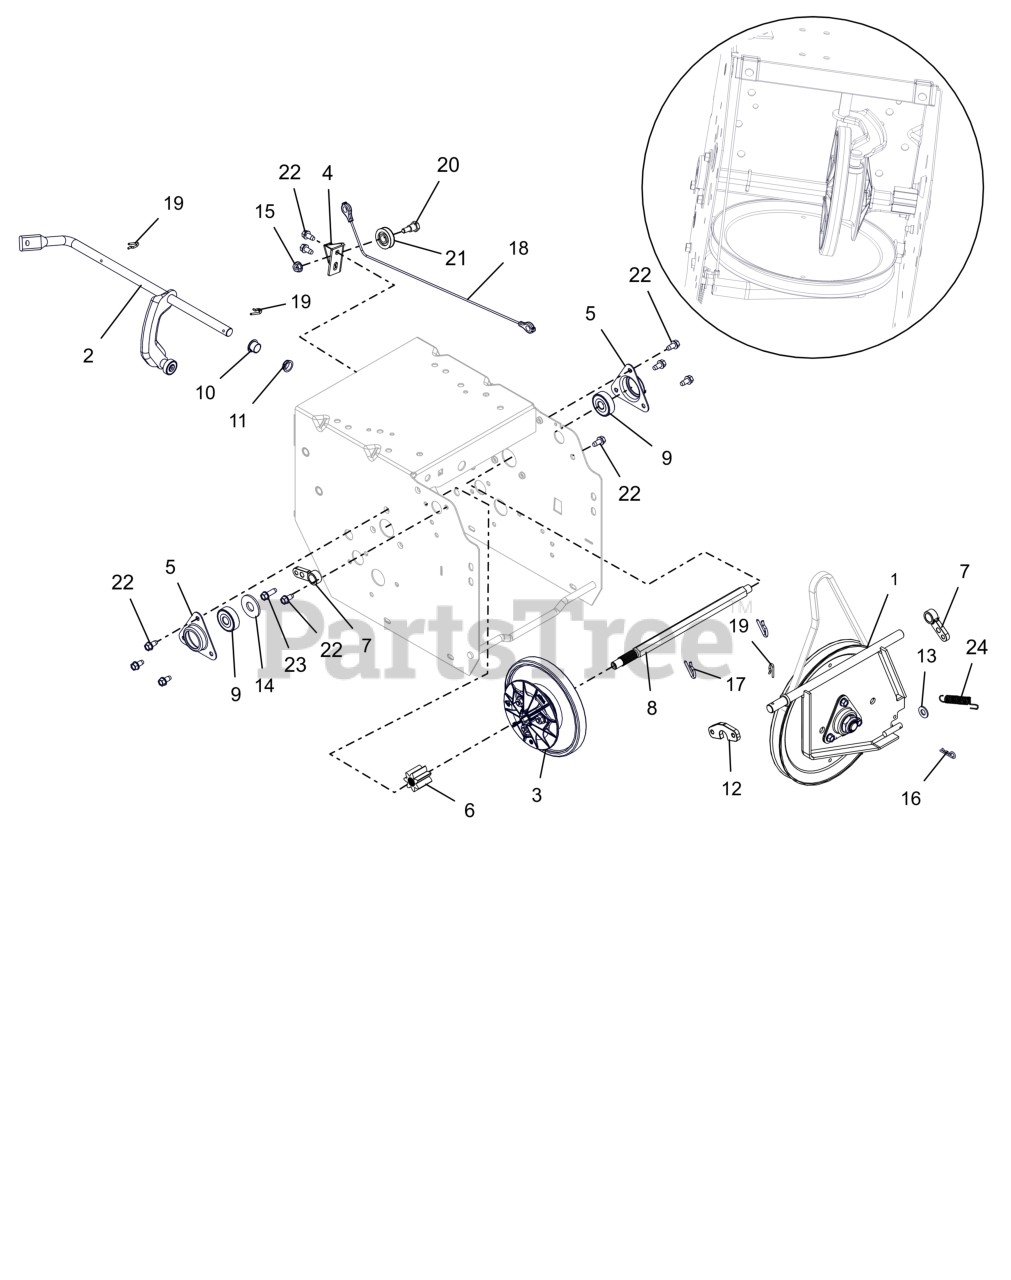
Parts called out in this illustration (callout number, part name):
1	PLATE, SWING - ASSEMBLY
2	ARM, SHIFT-SMALL DASH (ASSY)
3	DISC, FRICTION DRIVE-ASSEMBLY
4	BRACKET, CABLE PULLEY
5	FLANGE, BEARING
6	GEAR, PINION, 7 TOOTH W/SPLINE
7	SUPPORT BUSHING, SWING GATE
8	SHAFT, HEX W/SPLINE
9	BRG-BALL .437X1.375X.437
10	BUSHING, POLYLINER-.50 SPLIT
11	BUSHING, POLYLINER-.50 SNAPIN
12	SPACER, SWING GATE
13	WSHR,FLT .344X.688X.065 ZCC
14	WSHR,FLT .563X1.375X.109 ZCC
15	NUT-LK-CTR-FLG .25-20 ZC120
16	PIN, HAIR #213 .08X1.19 ZCC
17	PIN, SPRING CLIP
18	CABLE, LOWER TRACTION (CMPCT)
19	CLIP, SPRING
20	BOLT, SHLDR -.375 X .375 X .25-20
21	PULLEY, CABLE
22	SCR-TAP .25-20X.50 HWH ZCC
23	SCR,TAP .25-20X.75 HWH TR ZCC
24	SPRING, EXT. .043X.438X1.64
